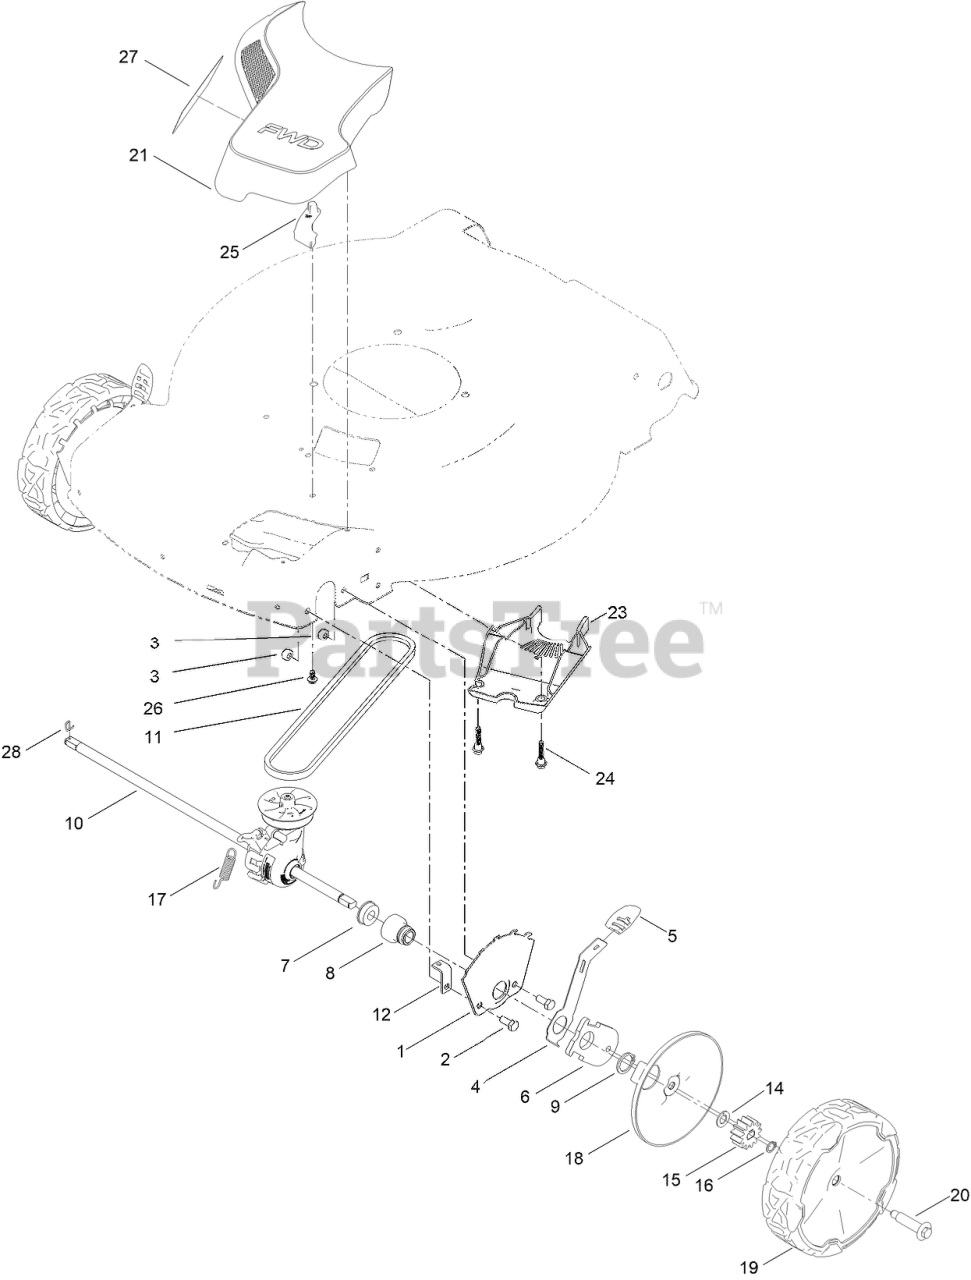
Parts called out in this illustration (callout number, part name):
1	PLATE-HOC,FRONT FSVQ WEDNESDAY
2	SCREW-HH
3	NUT-HEX
4	ARM-SPRING
5	KNOB-LEVER, HOC
6	ARM-PIVOT, FRONT
7	BEARING-BALL
8	RETAINER-BEARING, HOC
9	RING-RETAINING
10	TRANSMISSION-FWD
11	V-BELT
12	TAB-MOUNT, CABLE
14	WASHER-THRUST
15	GEAR-PINION, 13T
16	RING-RETAINING
17	SPRING-EXTENSION
18	ASM-COVER, WHEEL (DK GRAY)
19	ASM-8" WHEEL, FWD (BUSHINGS)
20	WHEEL BOLT
21	ASM-INTAKE, FWD
23	COVER-BELT, LOWER (FWD)
24	SCREW-SHOULDER, HHF
25	PAD-STOP
26	SCREW-PLASTIC,PH
27	DECAL-VORTEX AWD
28	PIN-SNAP
